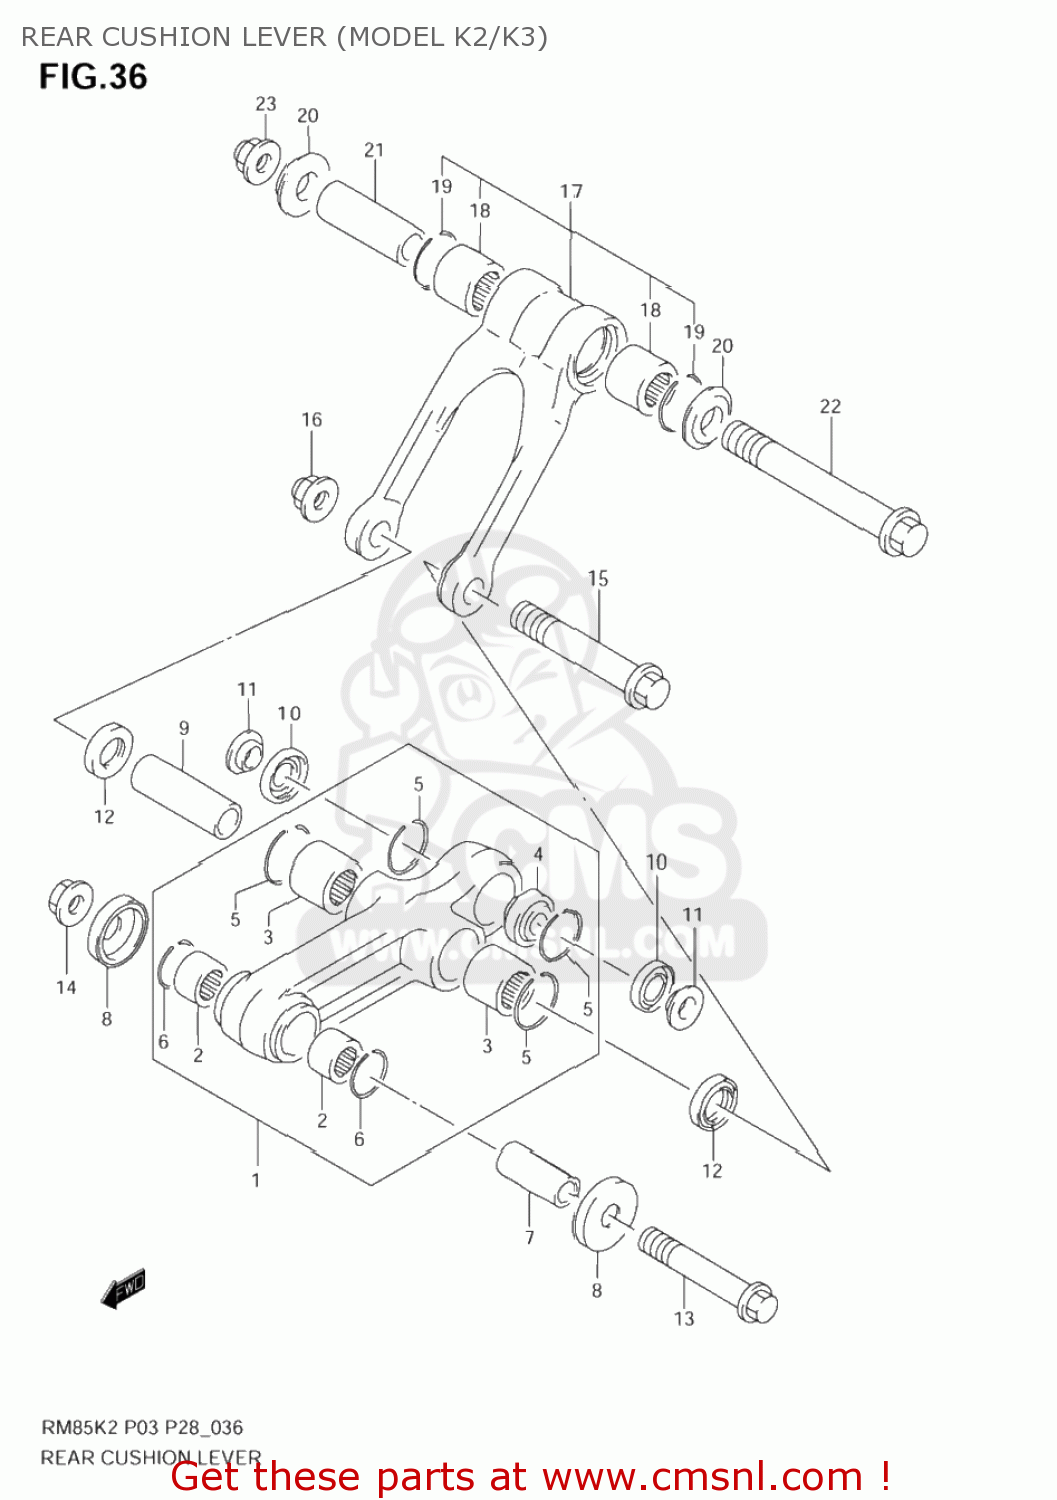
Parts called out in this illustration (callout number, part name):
1	LEVER SET,RR CUSHION
2	BEARING(14X20X12)
3	BEARING(17X24X20)
4	BEARING,RR CUSHION LEVER
5	RING,STOPPER
6	CIRCLIP,PISTON PIN
7	SPACER,RR CUSHION LEVER FR
8	SEAL,RR CUSHION LEVER FR DUST
9	SPACER,RR CUSHION LEVER CTR
10	SEAL,RR CUSHION LEVER RR DUST
11	SPACER,RR CUSHION LEVER RR
12	SEAL,OIL(17X24X3)
13	BOLT,RR CUSHION LEVER FR
14	NUT
15	BOLT,RR CUSHION LEVER CTR
16	NUT 12MM
17	ROD SET,RR CUSHION LEVER
18	BEARING(17X24X20)
19	RING,STOPPER
20	SPACER,RR CUSHION ROD SIDE
21	SPACER,RR CUSHION ROD
22	BOLT,RR CUSHION ROD
23	NUT 12MM
